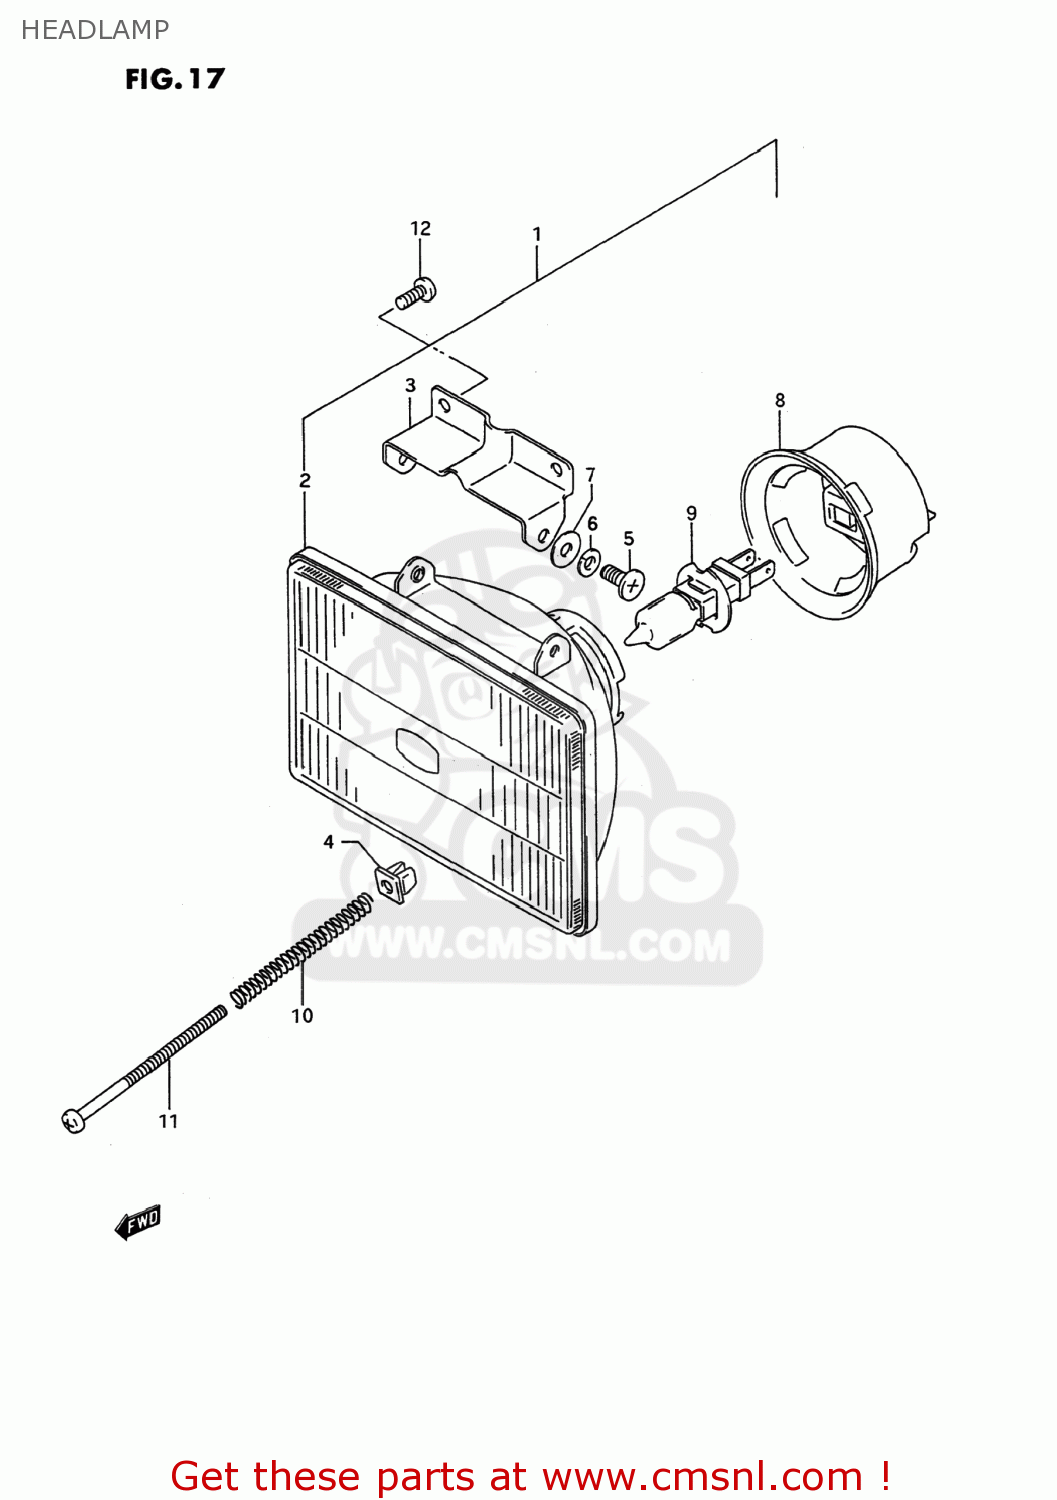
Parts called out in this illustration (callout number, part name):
1	HEADLAMP ASSY
2	UNIT,LAMP
3	BRACKET,LAMP
4	NUT,ADJUSTING
5	SCREW
6	WASHER,LOCK
7	WASHER
8	COVER,SOCKET
9	BULB(12V55W)
10	SPRING,HEAD LAMP ADJUSTER
11	SCREW(4X45)
12	SCREW
